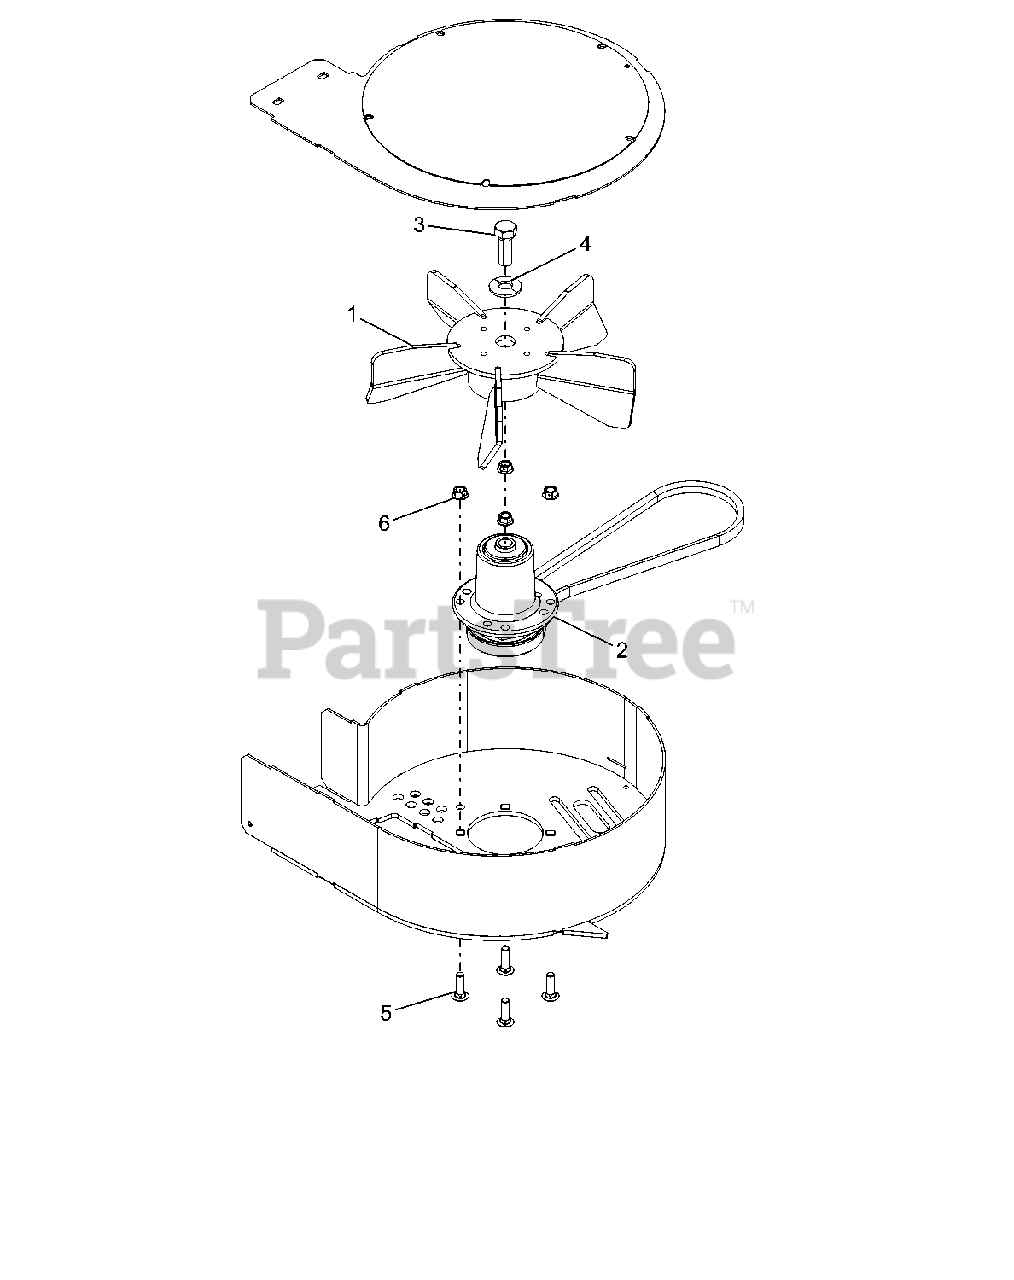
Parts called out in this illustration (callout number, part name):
1	WLDMT, FAN BAGGER
2	SPINDLE ASSEMBLY, SERVICE
3	BLT-HEX .62-18X1.75 GR8 YWZC
4	WSHR-BLVL .669X1.535X.138
5	@BLT-RDHDSQNK .38-16X1.25 G5YZ
6	NUT-LK-CTR-FLG .38-16 YWZC
